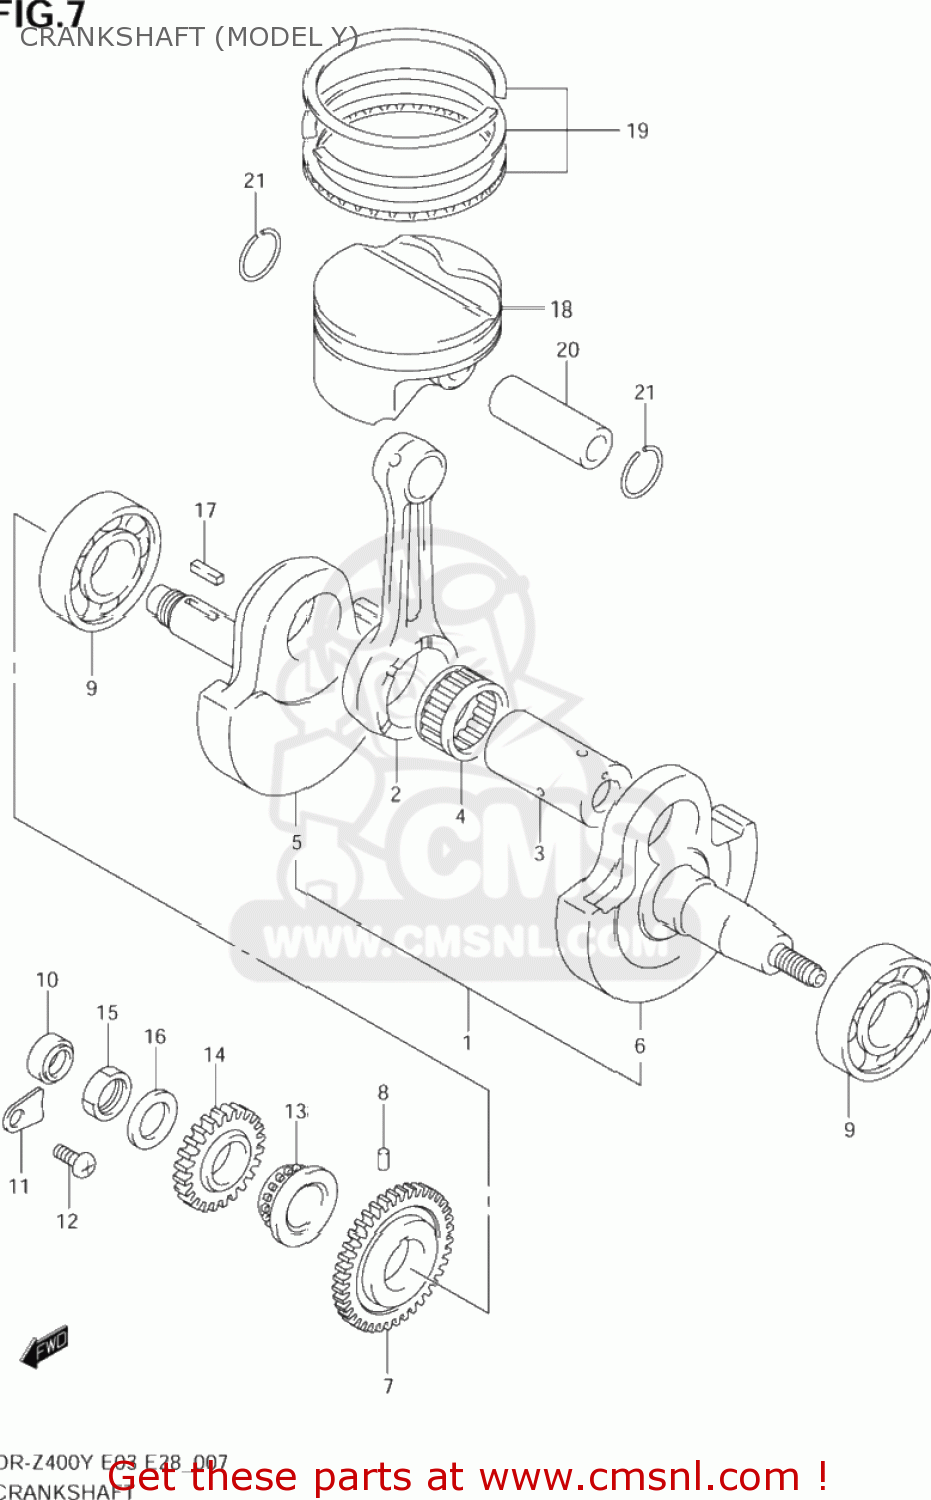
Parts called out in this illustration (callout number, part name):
1	CRANKSHAFT ASSY
2	CONNECTING ROD COMP
3	PIN COMP,CRANK
4	BEARING(35X43X22)
5	CRANKSHAFT,RIGHT
6	CRANKSHAFT,L
7	GEAR,CRANK BALANCER DRIVE
8	PIN(5X8)
9	BEARING(30X72X18)
10	SEAL,OIL(14X24X6)
11	RETAINER,BEARING
12	SCREW
13	SPROCKET,CAM CHAIN DRIVE
14	GEAR,PRIMARY DRIVE
15	NUT
16	WASHER
17	KEY
18	PISTON
19	RING SET,PISTON
20	PIN,PISTON
21	CIRCLIP,PISTON PIN
